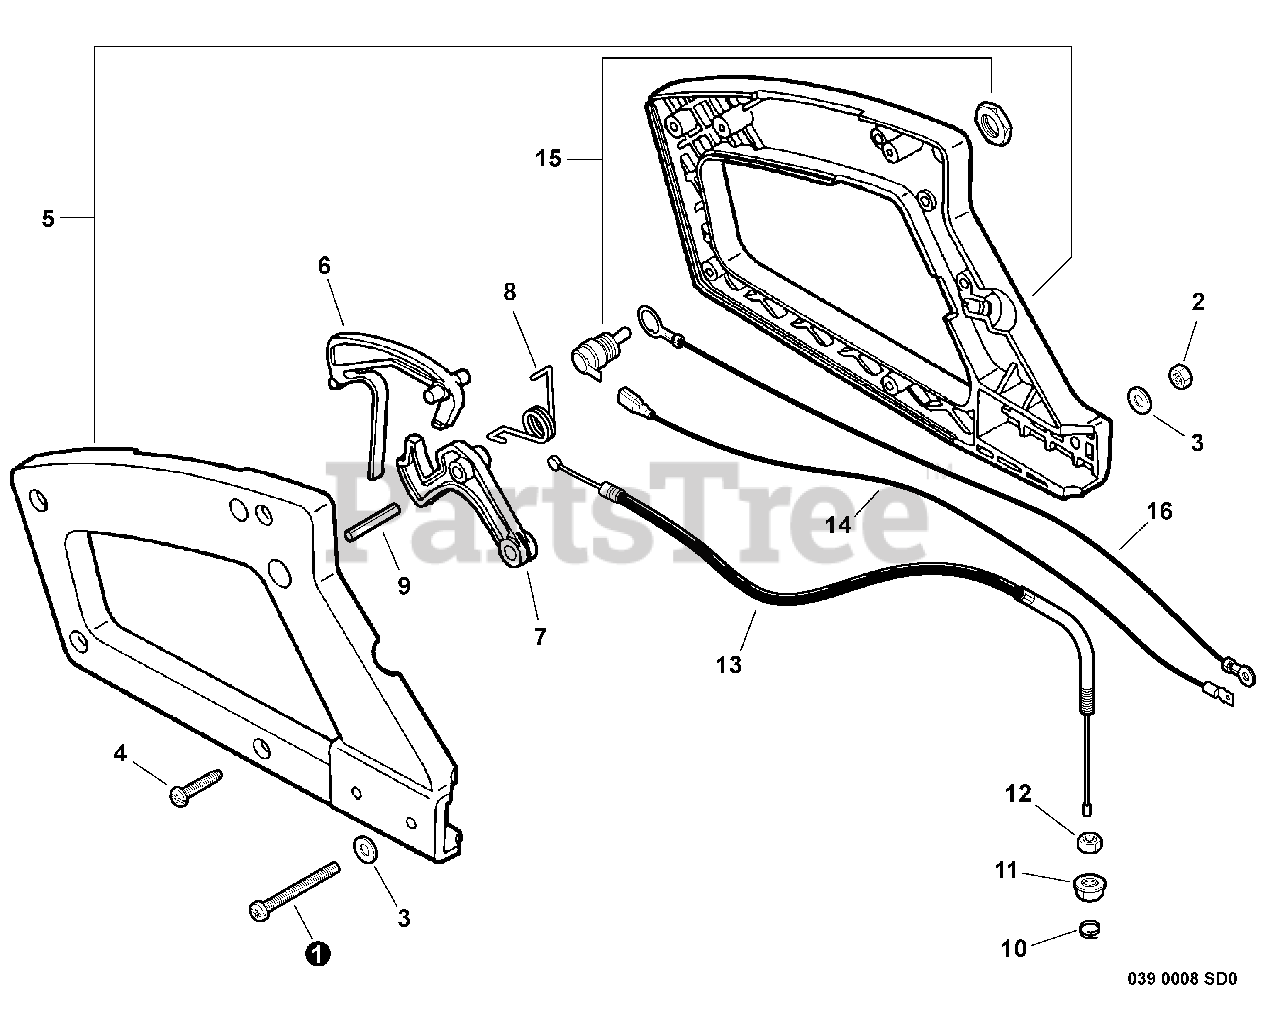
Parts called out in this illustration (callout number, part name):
1	SCREW - 5X40
2	LOCKNUT - 5
3	WASHER - 5
4	SCREW - 4X16
5	HANDLE ASSY - REAR
6	LEVER, TRIGGER LOCKOUT
7	TRIGGER, THROTTLE
8	SPRING, TRIGGER
9	PIN - SPRING -- 5X25
11	NUT - 6 -- FLANGE
13	CABLE, THROTTLE
14	LEAD - IGNITION
15	IGNITION SWITCH ASSY
16	LEAD - GROUND
